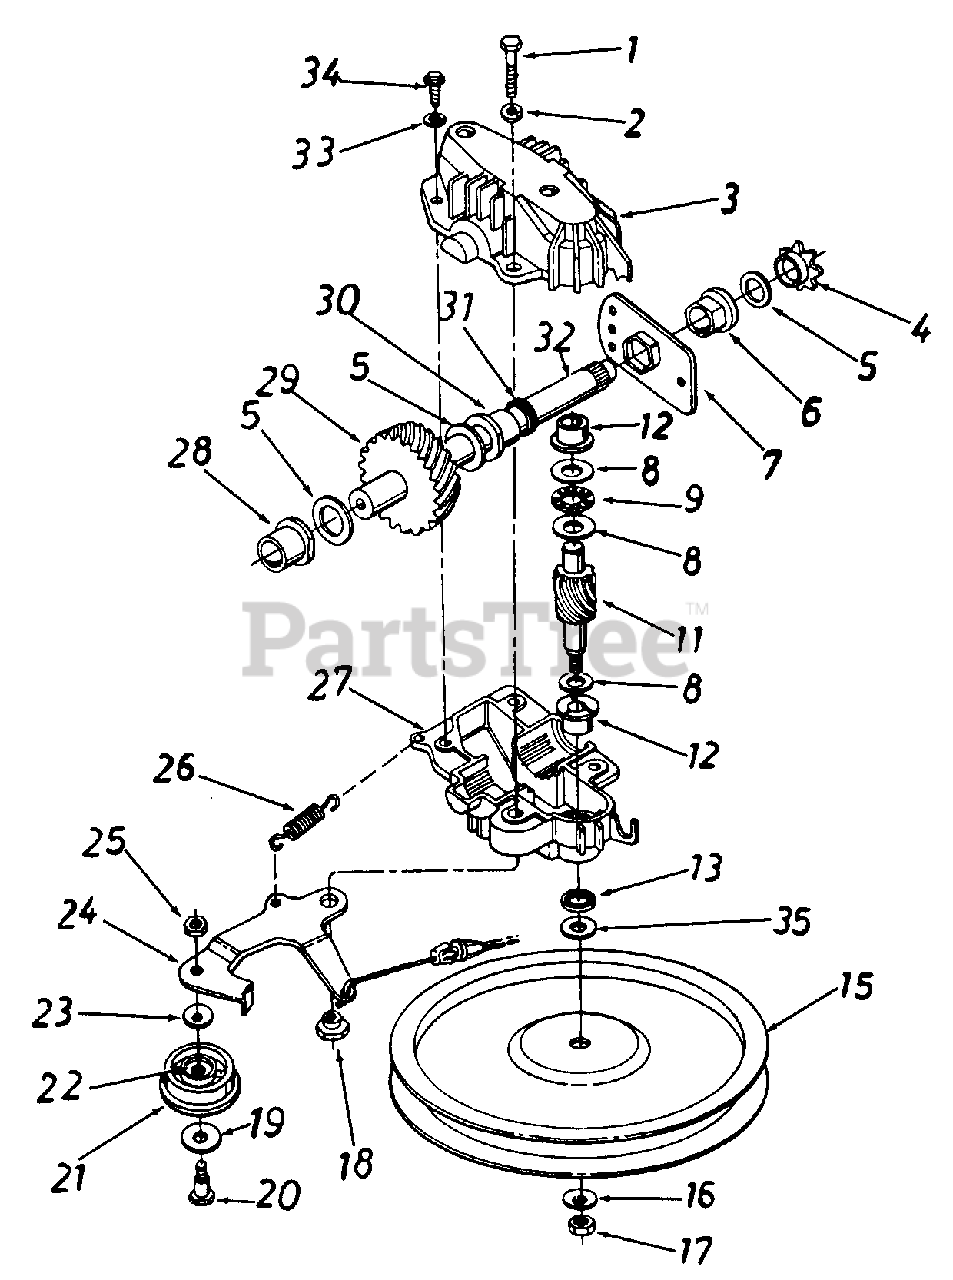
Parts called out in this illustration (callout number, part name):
1	SCREW-HEX
2	LOCK WASHER 1/4 DIA
3	HOUSING HALF-UPPER
4	SPROCKET-7T
5	WASHER-FL
6	BEARING-HEX FLANGE
8	WASHER-THRUST.382 X .684
9	BEARING-THRUST
11	SHAFT-PINION 11 T
12	BEARING-FLANGE
13	SEAL-OIL-.375 ID
16	WASHER-SPRING BELL
17	NUT-LH THD-1/4 X 28
18	SPACER-SHLD
19	WASHER-FL .995 X .032
20	SCREW-SHLD
21	KIT-PULLEY
22	BEARING-NEEDLE
23	WASHER-SPRING BELL
24	BRACKET ASSY-IDLER
25	NUT-HEX 1/4-28
26	SPRING-EXTENSION
27	HOUSING HALF-LOWER
28	BEARING-FLANGE
29	SHAFT-ASSY W/GEAR
30	BEARING-FLANGE
32	SHAFT-ASSY W/GEAR
33	WASHER-LOCK-#10
34	SCREW-HEX WASH HD TAP
35	WASHER-HEX
